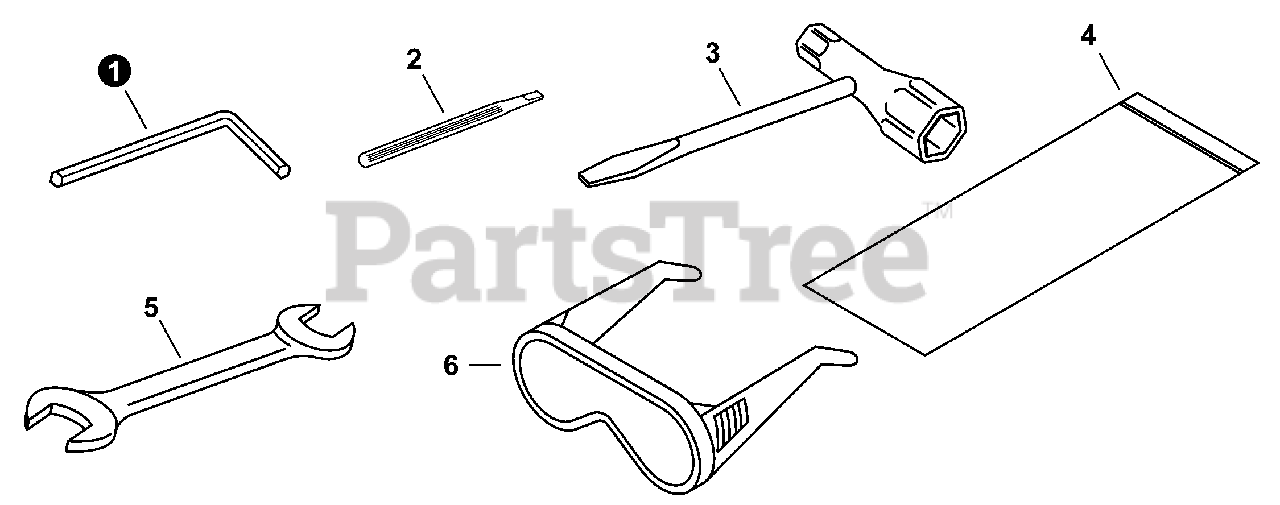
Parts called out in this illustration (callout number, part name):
1	WRENCH, ALLEN 4MM
2	SCREWDRIVER, PLASTIC
3	T-WRENCH 13×19mm
4	BAG, TOOL
5	SPANNER 8×10
6	GLASSES, SAFETY
